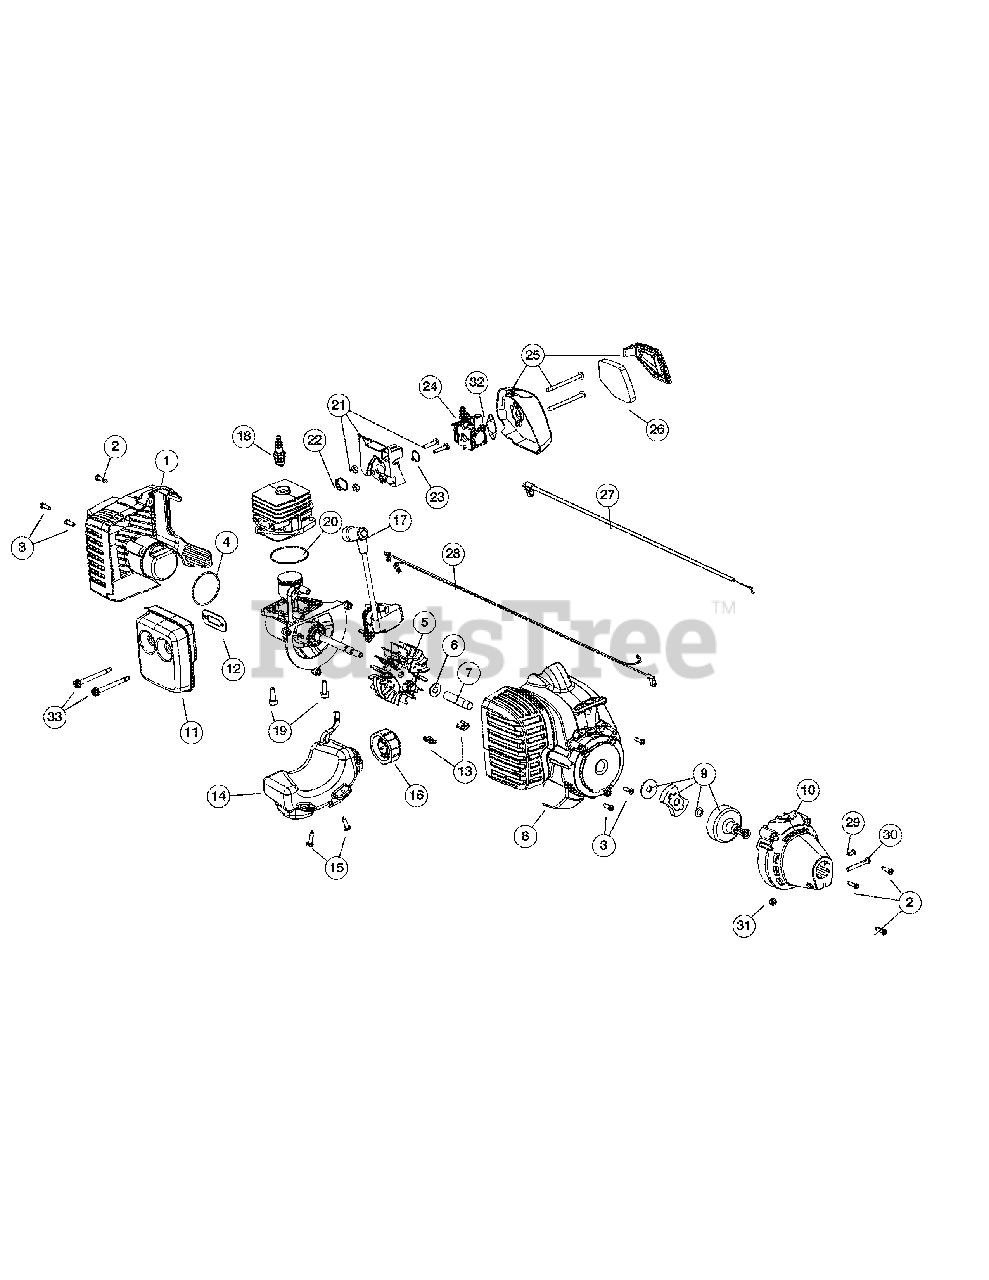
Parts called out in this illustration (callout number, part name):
1	Rear Cover Assembly
2	Cover Screw
3	Housing Screw
4	O-Ring
5	Flywheel Assembly
6	Washer
7	Spacer
8	Starter Housing
9	Starter Clutch Assembly
10	Clutch Cover
11	Muffler Assembly
12	Muffler Gasket
13	U-shaped Nut
14	Fuel Tank Assembly
15	Tank Screw
16	Fuel Cap
17	Module Assembly
18	Spark Plug
19	Crankcase Bolt
20	Crankcase O-Ring
21	Insulator Assembly
22	Insulator O-Ring
23	Carburetor O-Ring
24	Carburetor
25	Aircleaner Cover Assembly
26	Aircleaner Filter
27	Throttle Cable
28	Lead Wires
29	Anti-rotation Screw
30	Clamp Screw
31	Clamp Nut
32	Air Cleaner Gasket
33	Muffle Screws
